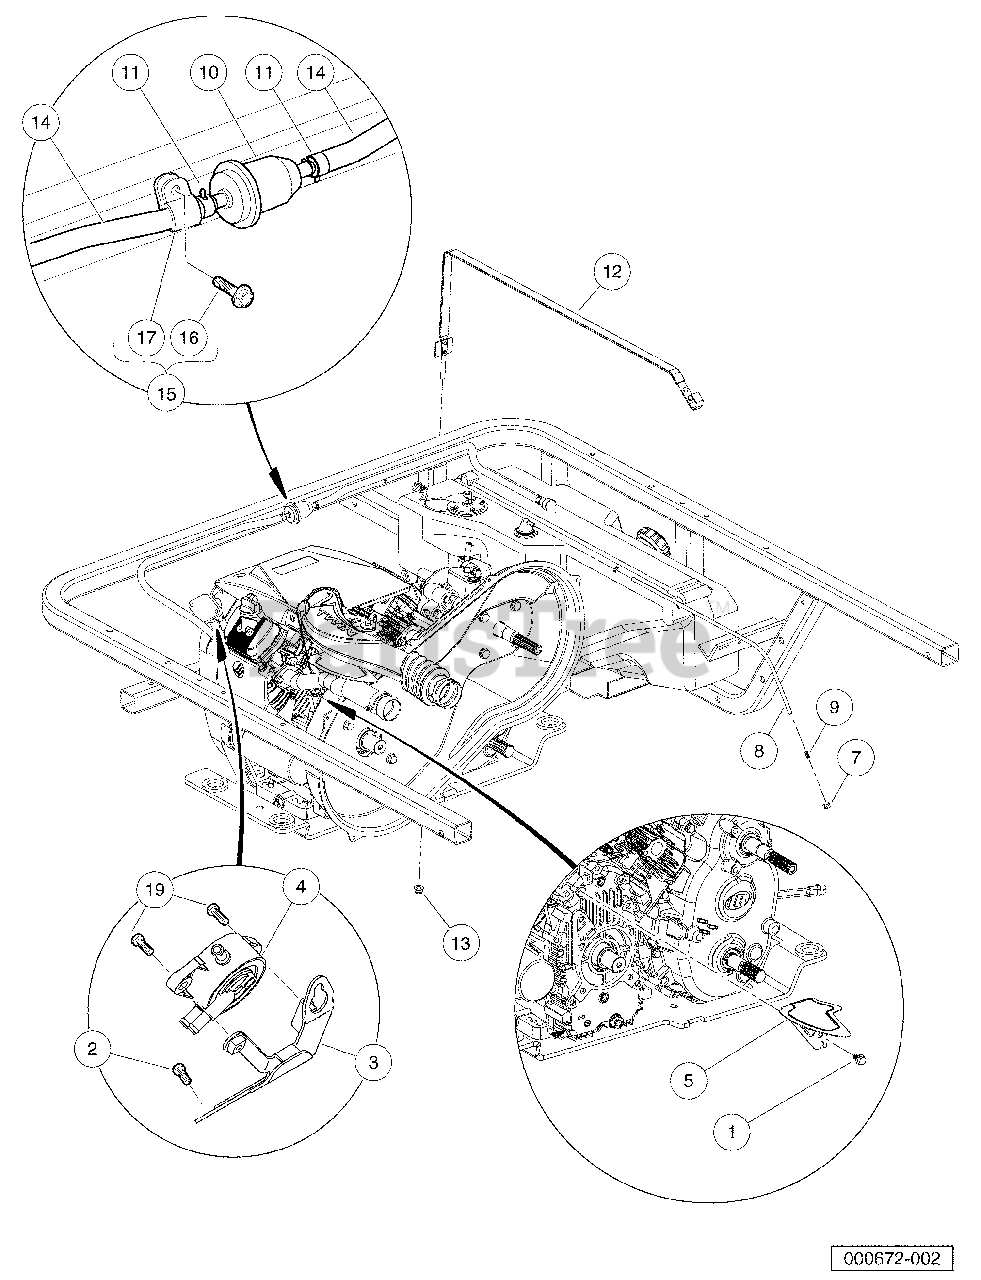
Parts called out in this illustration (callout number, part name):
1	Bolt Flanged Head, M8 X1.25x 16 with Loctite
2	Bolt, Flg, M6 X 1.0 X 16.
3	Bracket, Fuel Pump, Fh.
4	Pump, Fuel, Impulse, Fh.
5	Heat Shield, Header, Gas.
7	Clamp, 0.301 ID Hose.
8	Hose, Fuel, Vent, 22" Long.
9	Vent Barb.
10	Filter, Fuel, 30 Micron.
11	Clamp, Hose, Ctb 13mm.
12	Strap, Tank, Fuel.
13	Lock Nut, Flg M8 X 1.25 Nylon
14	Fuel Line.
15	Kit, Fuel Line Clamp, 4x4 Khi
16	Screw, M8X1.25X30, Hex.
17	P-clamp, Insulated 0.625 In
18	Instr, Kit Fuel Line 4x4 Khi
19	Bolt, Flanged, M6 X 20, Kaw
